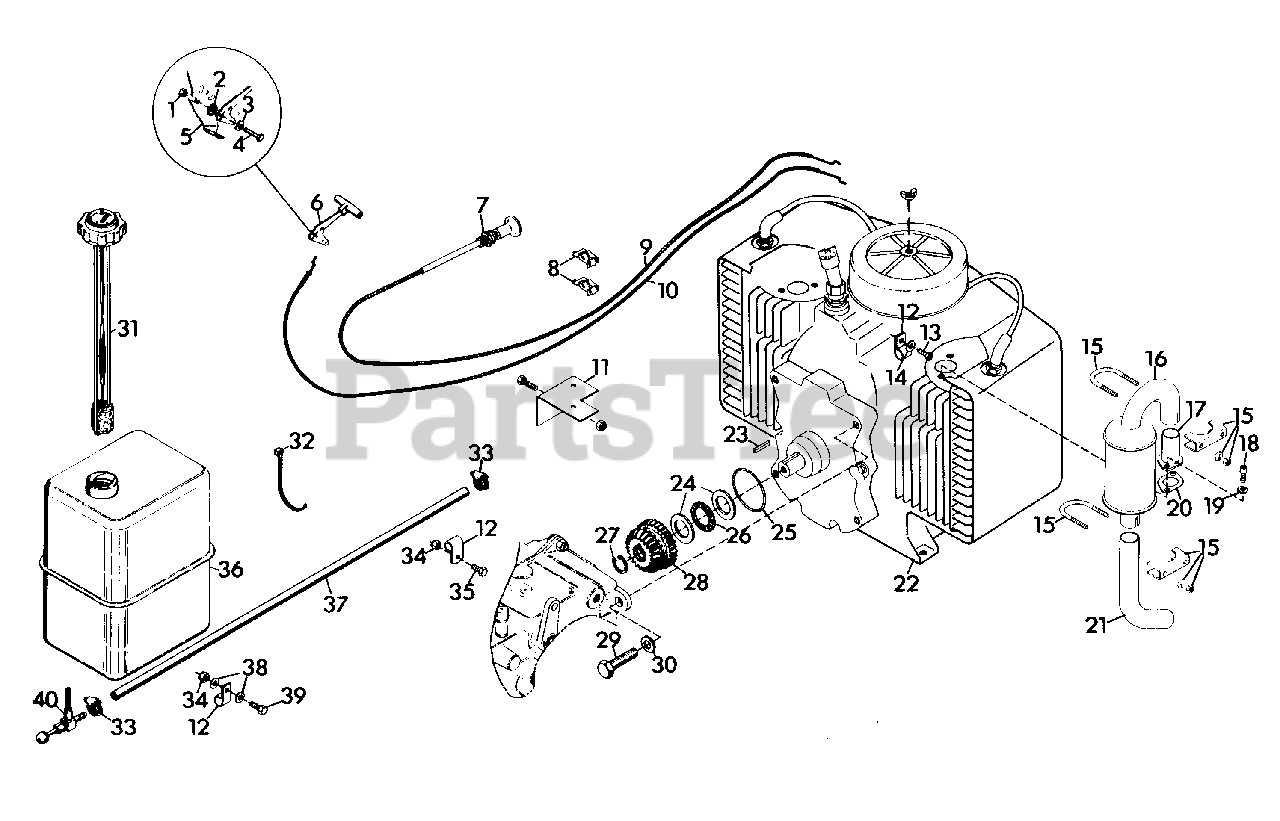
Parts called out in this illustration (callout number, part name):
1	NUT, LOCK 1/4-28
2	WASHER, FRICTION
3	WASHER, SPRING
4	BOLT, HEX 1/4-28X.75
5	BRACKET, MOUNTING
6	ASSEMBLY, KNOB AND LEVER
7	NUT, JAM 3/8-24 HEX
8	CLIP, SPEED
9	CONTROL, CHOKE
10	ASSEMBLY, CHOKE CONDUIT
11	BRACKET, THROTTLE AND CHOKE
12	CLAMP, NYLON
13	SCREW, TAPPING 1/4-20X.625 HHD ST
14	WASHER, FLAT .281X.625X.065
15	CLAMP, MUFFLER
16	MUFFLER
17	WELDMENT, HEADER
18	SCREW, CAP 5/16-18X.75 S/HD
19	WASHER, LOCK 5/16-18 REG.
20	GASKET, EXHAUST
21	EXTENSION, EXHAUST
22	ENGINE, 16 HP MAGNUM
23	KEY, SQUARE .250X1.250
24	RACE, BEARING THRUST 1.125X1.750X.123/.126
25	O-RING, 3.000X3.188X.094
26	BEARING, THRUST 1.127X1.740X.078
27	RING, RETAINING 1.125 SHAFT
28	GEAR, SPUR AND BEVEL, INPUT
29	BOLT, HEX 1/2-13X1.75
30	WASHER, LOCK 1/2 REG.
31	GAUGE, GAS
32	TIE, CABLE
33	CLAMP, HOSE
34	NUT, LOCK 5/16-18
35	BOLT, HEX 5/16-18X.75
36	TANK, FUEL
37	LINE, FUEL
38	WASHER, FLAT .344X.688X.065
39	BOLT, HEX 5/16-18X1.00
40	VALVE, FUEL 90 DEG. REVERSE FLOW
NS	NUT, LOCK 10-32
NS	SCREW, MACHINE 10-32X.50 PHD
